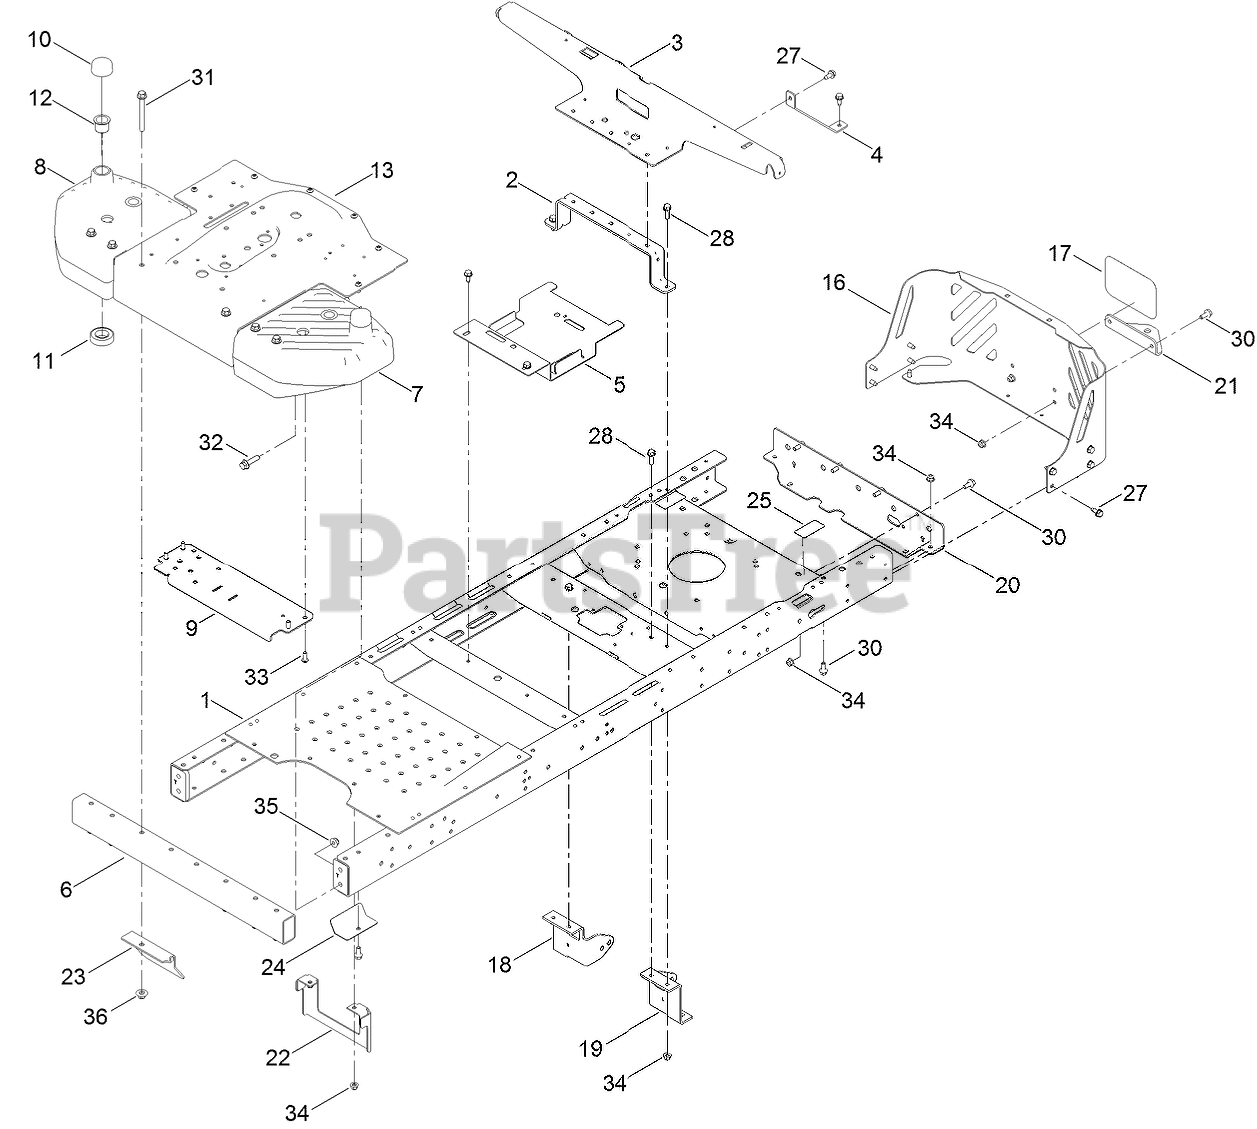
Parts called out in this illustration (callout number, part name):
1	FRAME ASM
2	BRACE-SEAT, REAR (NARROW)
3	SUPPORT-POD
4	SUPPORT-TANK, REAR
5	BRACKET-BATTERY
6	TUBE-FRONT, NARROW
7	HOUSING-SPINDLE, LH
8	HOUSING-SPINDLE, RH
9	PLATE-BRIDGE, NARROW
10	CAP-CASTER
11	BEARING-BALL
12	BUSHING-PIVOT
13	PAN-STEER, FRONT
16	GUARD-ENGINE, NARROW
17	DECAL
18	MOUNT-HYDRO, FRONT (RH)
19	MOUNT-HYDRO, FRONT (LH)
20	CROSSMEMBER-REAR, NARROW
21	BRACKET-HITCH
22	BRACKET-UPSTOP
23	GUARD-FRONT
24	PLATE-GUARD
25	DECAL-BYPASS
27	SCREW-HWHTF
28	SCREW-HHF
30	SCREW-HHF
31	SCREW-HHF
32	SCREW-HHF
33	SCREW-HSBH
34	NUT-HF, NI
35	NUT-HF, NI
36	NUT-FLANGE, NI
